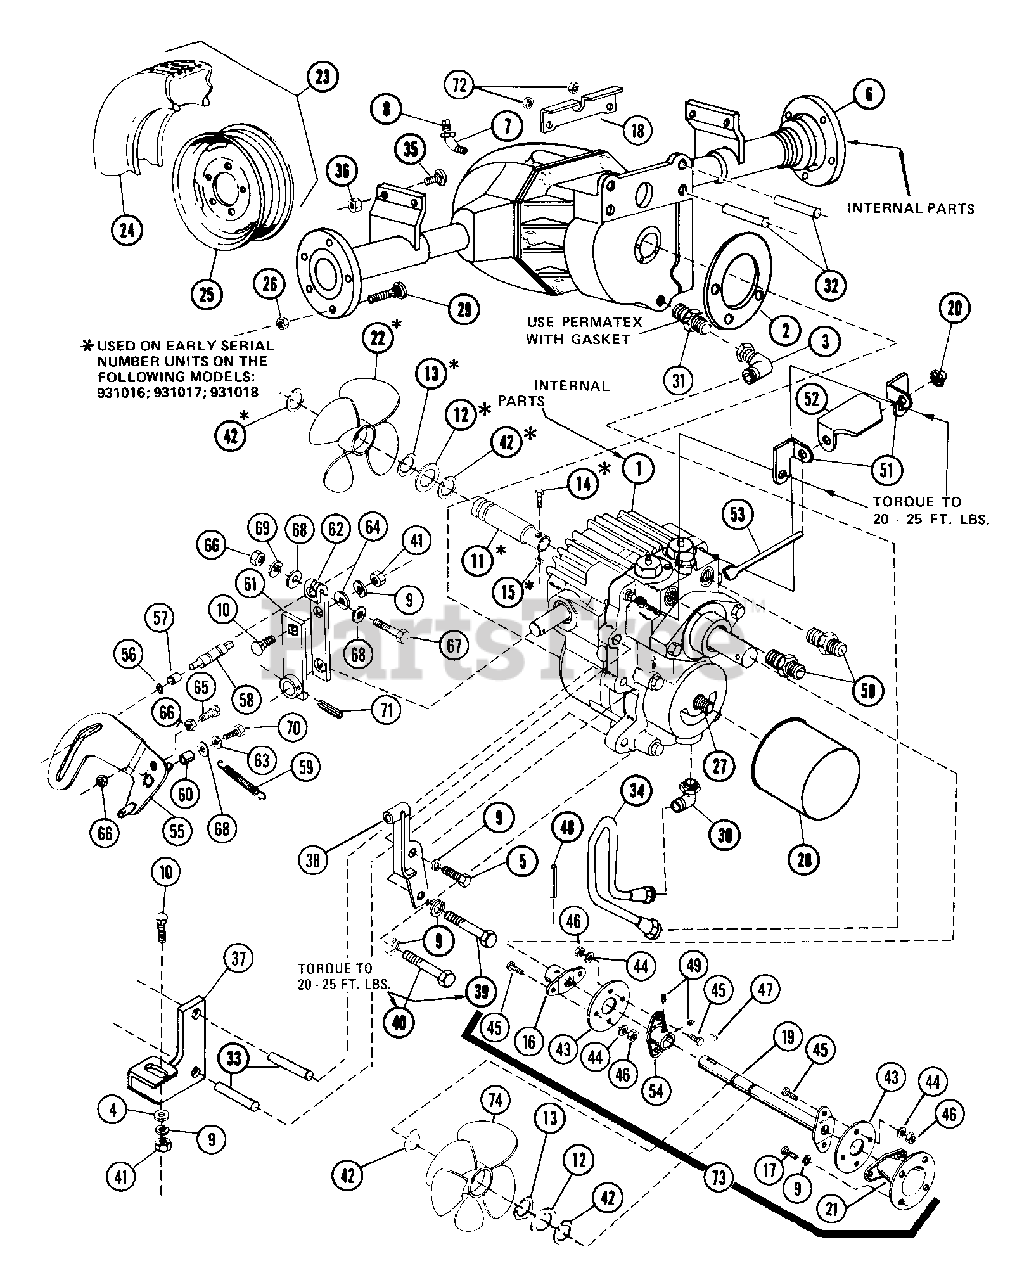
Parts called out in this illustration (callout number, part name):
1	12, 14, & 16 H.P. TRANSMISSION
3	SWIVEL 90 DEGREE ELBOW
4	WSHR-FL-STL .438X1.0X.083 PL
5	BLT-HEX .38-16X1.50 PL GR2
6	REAR AXLE & SUPPORTS
7	STREET ELBOW 1/2 X 45
8	PIPE PLUG
9	WSHR-LK .375X.094 MED PL
10	BLT-RDHDSQSHNK .38-16X1.00 PL
12	WSHR-FL-STL 1.016X1.625X.045
12	WSHR-FL-STL .781X1.500X.060
13	WAVE WASHER 1.015X1.50X.174
13	SPRING WASHER
14	BLT-HEX .25-20X1.25 PL GR5
15	NUT-LK-CTR .250-20 PL
16	COUPLING
17	BLT-HEX .38-16X.63 PL GR2
18	TORQUE BRACKET
19	DRIVE SHAFT ASSY
20	PUSH NUT, .312
21	DRIVE COUPLING
23	REAR TERRA TIRE 23X10.50X12
23	REAR TERRA TIRE
24	TIRE
25	WHL
25	WHL 12X8.50
26	NUT-LUG .437-20 YWZC
28	OIL FILTER
29	BLT-WHL-LUG .44-20X1.38 DANA
30	90 DEGREE ELBOW O RING
31	CONNECTOR
32	SPACER .379X.625X3.480
33	SPACER .379X.625X3.298
34	TUBE ASSEMBLY
35	BLT-RDHDSQNK .50-13X1.25 PL
36	NUT-LK-CROWN .50-13 GR C PL
37	BRACKET
38	CAM PIVOT BRACKET
39	BLT-HEX .38-16X5.00 PL GR2
40	BLT-HEX .38-16X4.75 PL GR2
41	NUT-HEX .375-16
42	RG-RTNG-EXT 1.00X.042
42	RG-RTNG-EXT .750X.042
43	SPACER COUPLING
44	WSHR-FL-STL.312X.734X.065PL
45	BLT-HEX .31-18X.50 PL GR2
46	NUT-LK .312-18 GR A PL
47	KEY-WDRF .188X.75X.313 SAE 9
48	PIN-ROLL .250X1.25
49	SCR-SET .32-18X.38 SKHCUPNL OH
50	CONNECTOR
51	SUPPORT
53	PIVOT ROD
54	COUPLING HUB
56	RG-RTNG-EXT .312X.025
57	CAM ROLLER
58	PIN ECCENTRIC
59	SG-TENS .060X.75X2.81 WLD 6
63	WSHR-FL-STL .531X1.062X.095 PL
64	WSHR-FL-STL.406X.812X.065PL
65	BLT-HEX .25-20X1.00 GR2
66	NUT-HEX .250-20 PL
67	BLT-HEX .25-20X2.00 PL GR5
68	WSHR-FL-STL.281X.62X.065 PL
69	WSHR-LK .250X.077 HVY PL
70	BLT-SERHFWH .25-20X.50 PL
71	PIN-ROLL .250X1.38
72	NUT-LK-CTR .312-24 PL
73	DRIVE SHAFT ASSY HYDRO
